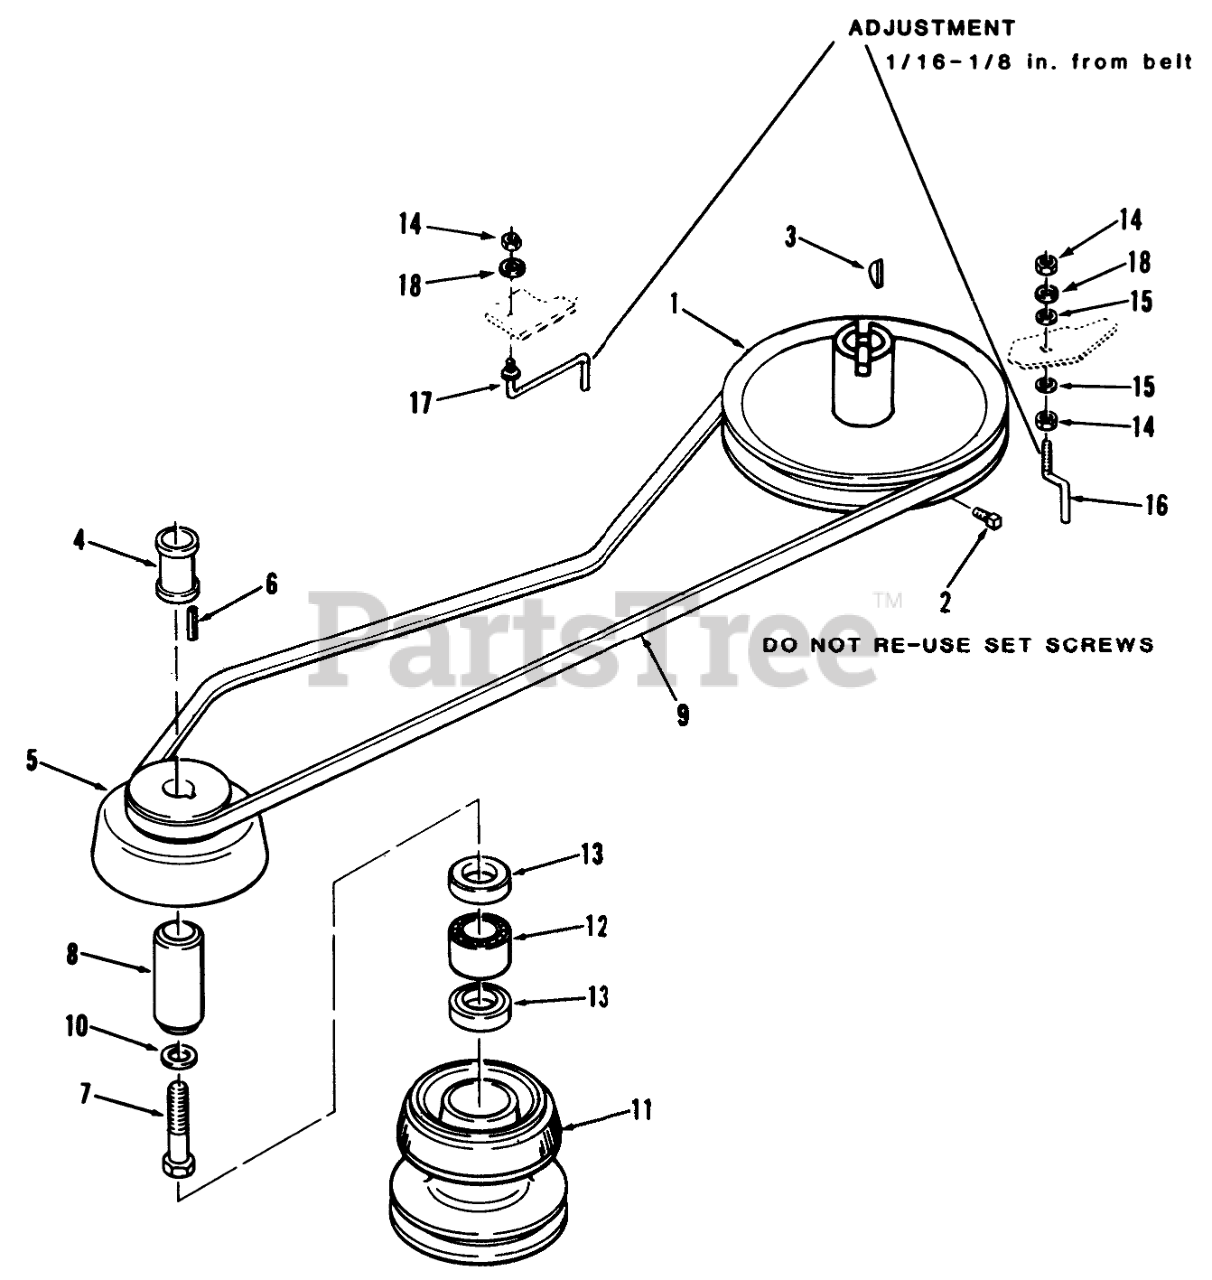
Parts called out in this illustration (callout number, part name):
1	PULLEY-TRANS (B)
2	SCREW-SQH
3	KEY-HI-PRO
4	SPACER-TUBE
5	PULLEY-ENGINE
7	HEX HD CAP SCREW
8	RACE-BEARING
9	V-BELT
10	Special Washer 227-5
11	ASSY PULLEY MWR DR
12	BRG-NEEDLE OPEN END
13	SEAL-OIL
14	NUT-HEX
15	WASHER-PLAIN
16	GUIDE-BELT
17	GUIDE-BELT
18	WASHER-LOCK
